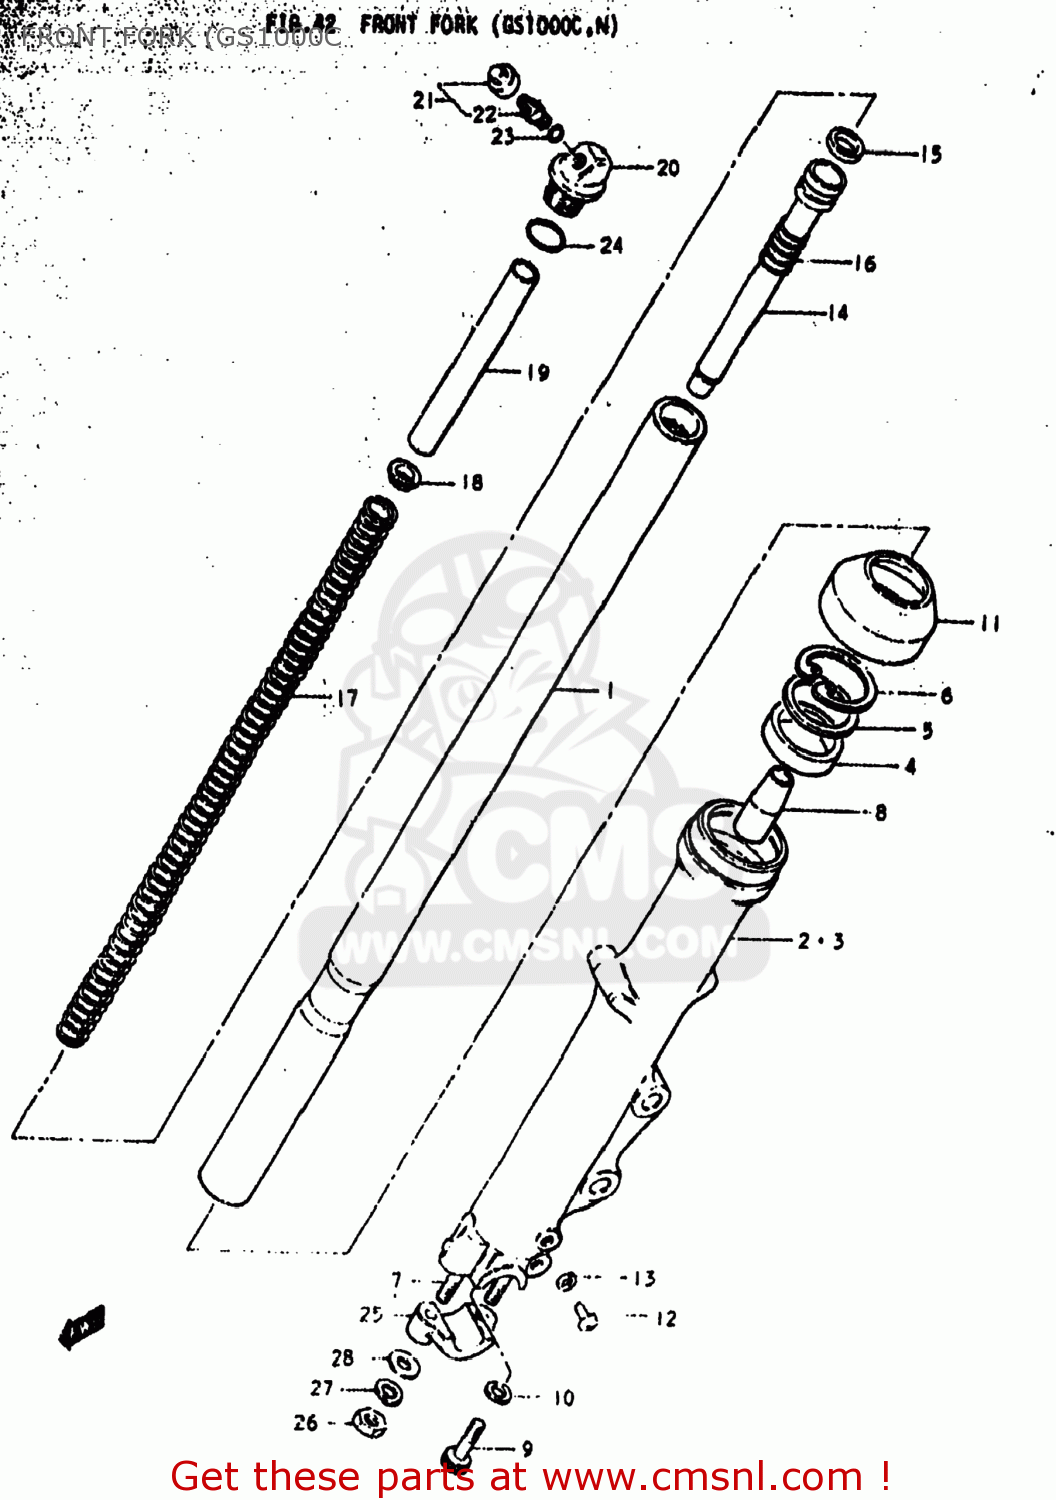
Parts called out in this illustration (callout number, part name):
0	DAMPER SET
1	TUBE,FORK,INNER
2	TUBE,FORK,OUTER,RIGHT
3	TUBE,OUTER,LEFT
4	OIL SEAL,FRONT FORK
5	WASHER. FRONT FORK
6	CIRCLIP,FORK OIL SEAL
7	STUD BOLT
8	PIECE,OIL LOCK
9	BOLT,FORK CYLINDER(10X25)
10	GASKET (NAS)
11	SEAL,DUST
12	SCREW
13	GASKET,DRAIN,PLUG (NAS)
14	CYLINDER,FRONT FORK
15	RING,PISTON
16	SPRING,REBOUND
17	SPRING,FRONT FORK
18	GUIDE,FRONT FORK SPRING C
19	SPACER,FRONT FORK SPRING
20	CAP
21	VALVE & CAP ASSY
22	VALVE
23	O RING
24	O RING
25	HOLDER,AXLE
26	NUT (8MM)
27	LOCK WASHER
28	WASHER
